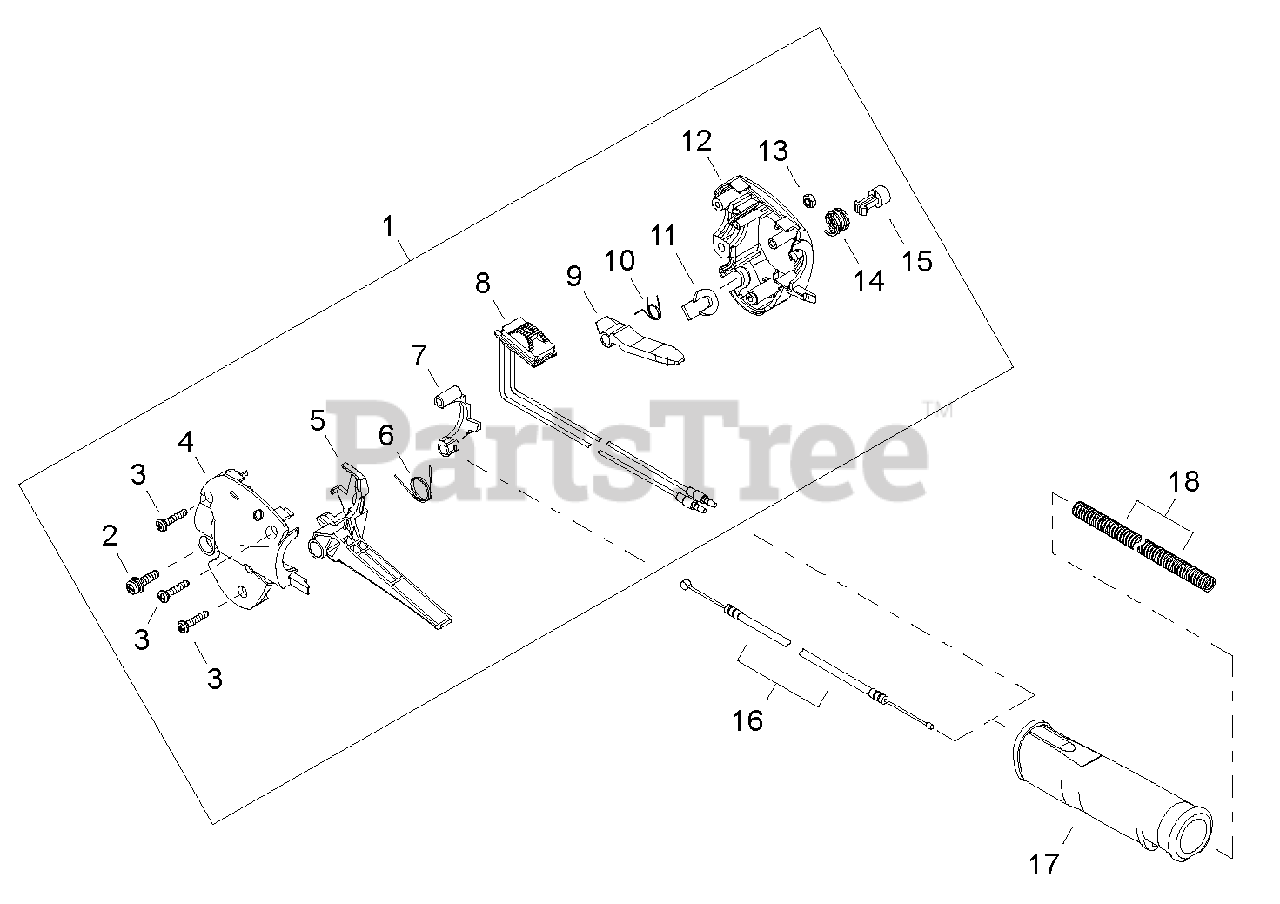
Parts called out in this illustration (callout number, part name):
1	THROTTLE CONTROL ASSY
2	SCREW M5×20
3	SCREW, TAPPING M4×20
4	CONTROL HANDLE - LEFT
5	TRIGGER, THROTTLE
6	SPRING, THROTTLE RETURN
7	LOCKOUT, THROTTLE
8	SWITCH, ON-OFF
9	LEVER, THROTTLE LOCKOUT
10	SPRING, THROTTLE LOCKOUT
11	PLUG
12	CONTROL HANDLE - RIGHT
13	NUT M5
14	SPRING, COMPRESSION
15	BUTTON, THROTTLE LOCK
16	CABLE, THROTTLE
17	GRIP
18	TUBE, PLASTIC PROTECTIVE
